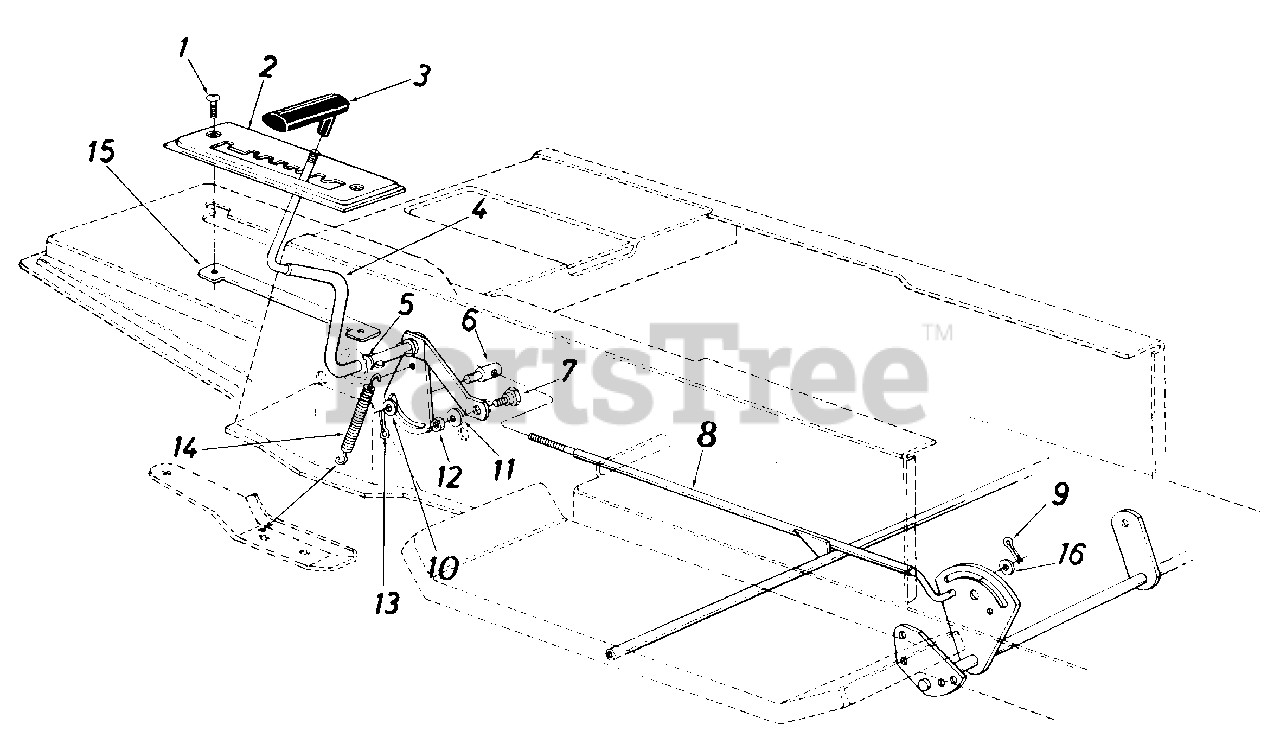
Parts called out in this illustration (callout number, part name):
1	Truss Mach. Scr. 1/4-20 x .75" Lg.
4	Speed Selector Cam Ass'y.
5	Flat Washer .53" I.D. x .93" O.D.
6	Ferrule 3/8-24 x .37" Dia.
7	Shoulder Bolt .435" Dia. x .160
8	Speed Control Rod Ass'y.
9	Cotter Pin 3/32" Dia. x .75" Lg.
10	Fl-Wash. .39" I.D.
11	L-Wash. 5/16" I.D.
12	Hex Nut 5/16-18 Thd.
13	Hairpin Cotter 118" Dia.
14	Spring
15	Clamping Plate
16	Fl-Wash. .47" I.D. x .88" O.D.
